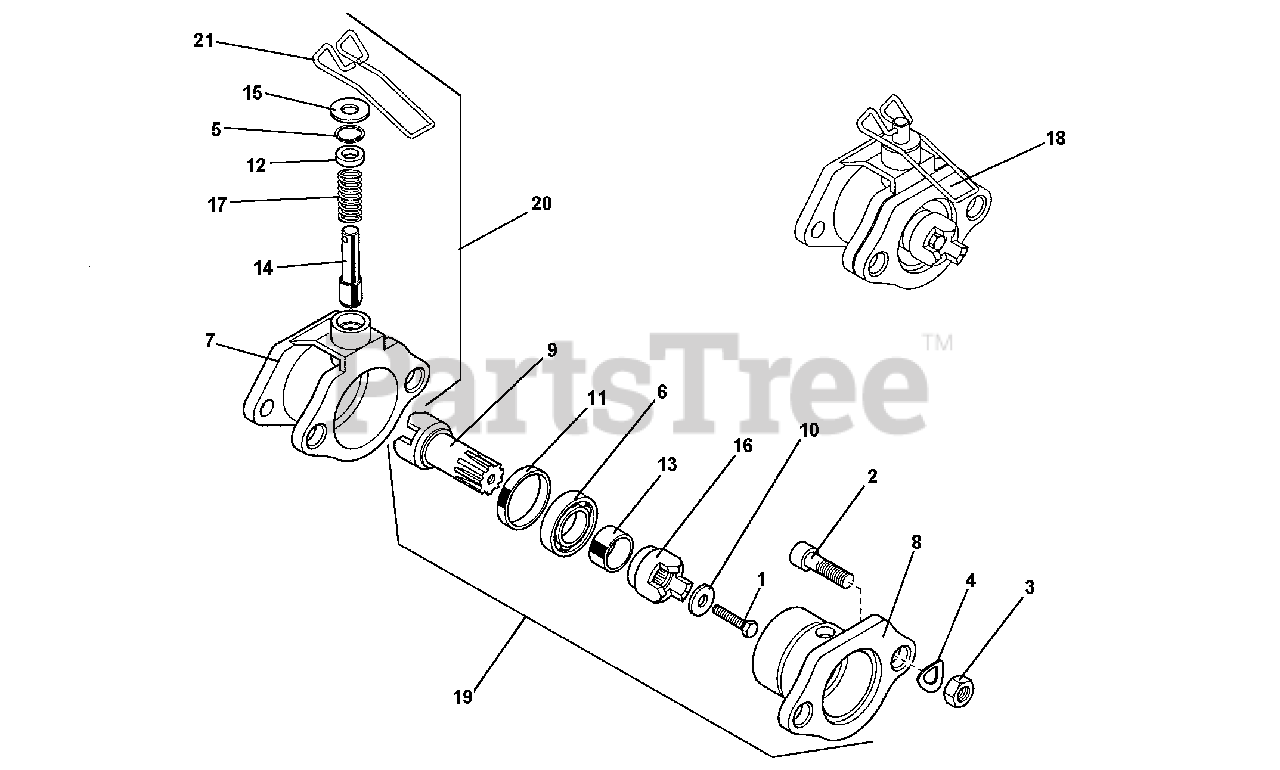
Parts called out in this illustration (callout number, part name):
1	SCREW, M6 X 20
2	SCREW M12 X 45
3	NUT, SELF LOCKING M12
4	WASHER, LOCK M12
5	CIRCLIP, INTERNAL
6	BEARING M12 X 47 X 12
7	BUSHING FOR QUICK HITCH
8	TANG CASE FOR QUICK HITCH
11	EXTENSION RING
13	RING FOR COUPLER
16	3-DOG COUPLING
18	QUICK HITCH ASSEMBLY
19	QUICK HITCH TANG
20	QUICK HITCH BUSHING
